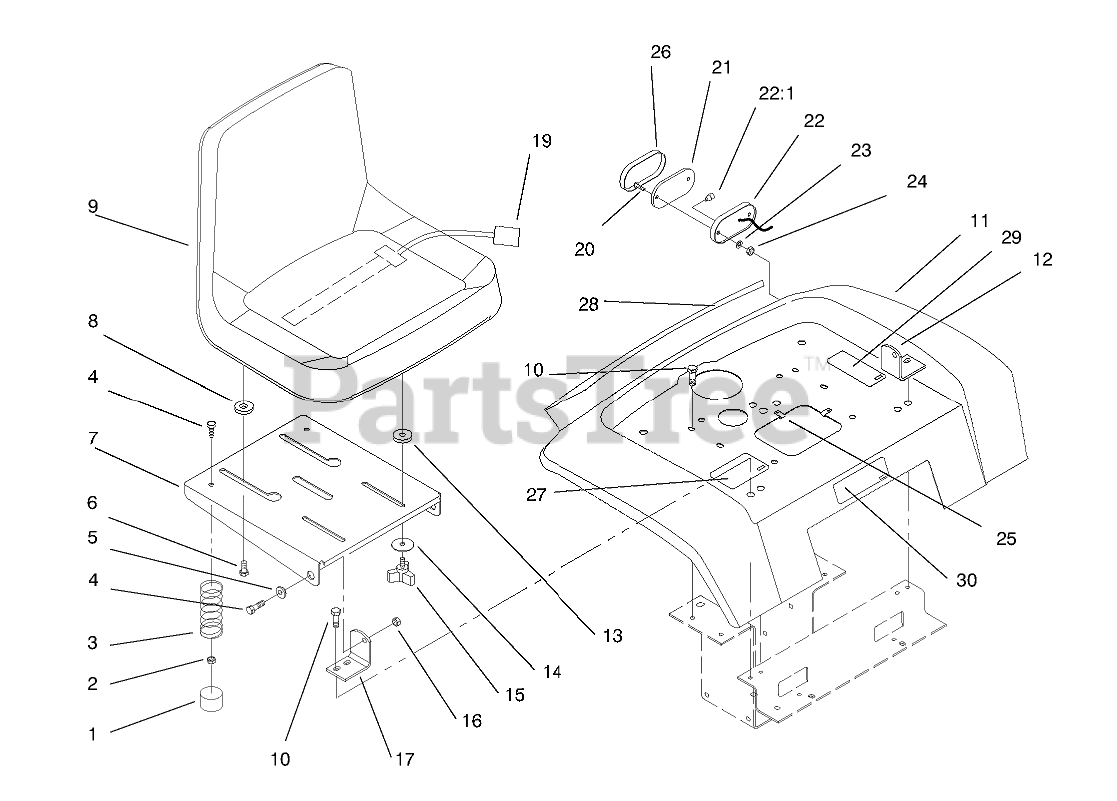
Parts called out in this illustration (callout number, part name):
1	CAP-PROTECTOR
2	NUT-LOCK, NI
3	SPRING-COMPRESSION
4	SCREW-HH
5	BUSHING
6	BOLT-SHOULDER
7	SUPPORT - SEAT (BLACK)
8	SPACER-NYLON
9	SEAT-V-511
10	Bolt
12	BRACKET-PIVOT, LH
13	SPACER-NYLON
14	WASHER
16	NUT-LOCK, NI
17	BRACKET-PIVOT, RH
19	SWITCH-SEAT
20	SCREW-PPH
22	BASE-TAIL LIGHT
23	WASHER-LOCK, INT
24	NUT-LOCK, NI
25	SPEED CLIP
26	LENS-TAIL LIGHT
27	DECAL-DO NOT TOW
28	DECAL - REAR FENDER
30	DECAL - USA
